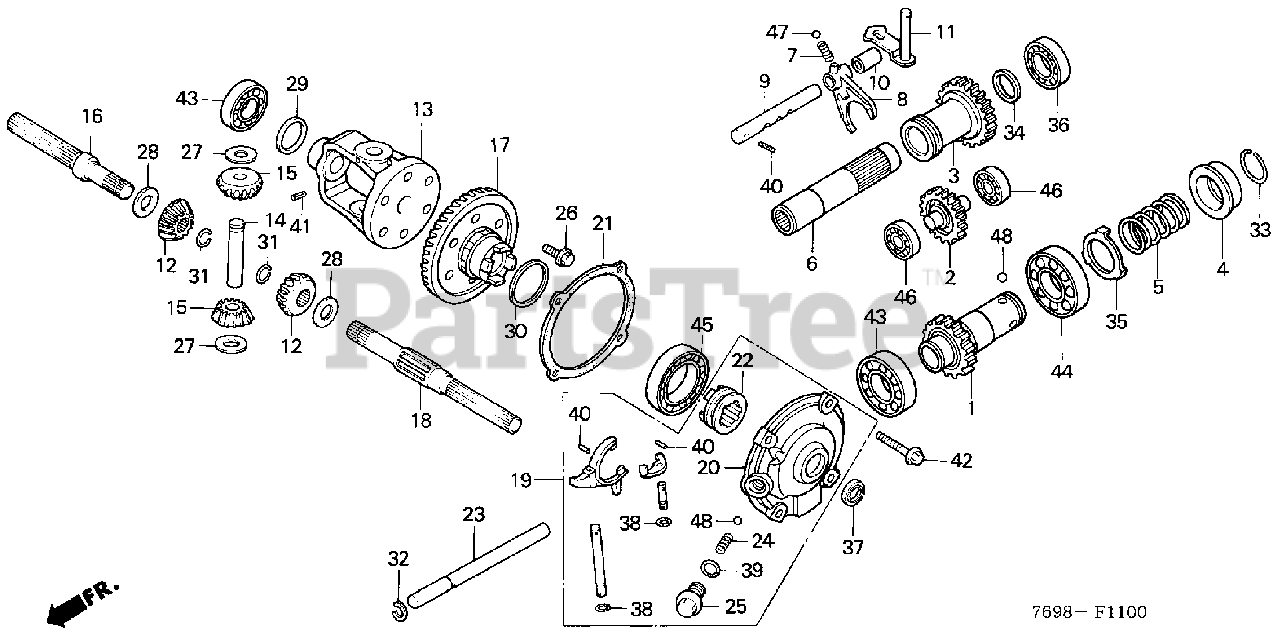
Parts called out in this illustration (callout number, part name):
1	SHAFT, P.T.O. OUTPUT
2	SHAFT, P.T.O. IDLE
3	GEAR, P.T.O. CHANGE
4	COLLAR, P.T.O. TUBE
5	SPRING, P.T.O. TUBE
6	SHAFT, P.T.O. INPUT
7	SPRING B, BALL SETTING
8	FORK, P.T.O. SHIFT
9	SHAFT, P.T.O. SHIFT
10	COLLAR, P.T.O. SHAFT
11	ARM, P.T.O. SHIFT
12	GEAR, DIFFERENTIAL (14T)
13	CASE, RR. DIFFERENTIAL
14	SHAFT, DIFFERENTIAL PINION
15	PINION, DIFFERENTIAL (14T)
16	SHAFT, R. RR. DRIVE
17	GEAR, RR. DIFFERENTIAL DRIVEN
18	SHAFT, L. RR. DRIVE
19	HOLDER, DIFFERENTIAL BEARING
21	GASKET, DIFFERENTIAL BEARING HOLDER
22	SHIFTER, DIFFERENTIAL LOCK
23	SHAFT, DIFFERENTIAL LOCK
24	SPRING, DIFFERENTIAL LOCK FORK
25	SCREW, BALL SET SPRING
26	BOLT, HEX. (10MM)
27	WASHER A, DIFFERENTIAL PINION (16.2X30X0.7)
27	WASHER B, DIFFERENTIAL PINION (16.2X30X0.8)
27	WASHER C, DIFFERENTIAL PINION (16.2X30X0.9)
27	WASHER D, DIFFERENTIAL PINION (16.2X30X1.0)
28	WASHER, DIFFERENTIAL GEAR
29	SHIM, RR. DIFFERENTIAL CASE (35.5X45X1.0) (A)
29	SHIM, RR. DIFFERENTIAL CASE (35.5X45X1.1) (B)
29	SHIM, RR. DIFFERENTIAL CASE (35.5X45X1.2) (C)
29	SHIM, RR. DIFFERENTIAL CASE (35.5X45X1.3) (D)
29	SHIM, RR. DIFFERENTIAL CASE (35.5X45X1.4) (E)
29	SHIM, RR. DIFFERENTIAL CASE (35.5X45X1.5) (F)
29	SHIM, RR. DIFFERENTIAL CASE (35.5X45X1.6) (G)
29	SHIM, RR. DIFFERENTIAL CASE (35.5X45X1.7) (H)
29	SHIM, RR. DIFFERENTIAL CASE (35.5X45X1.8) (I)
29	SHIM, RR. DIFFERENTIAL CASE (35.5X45X1.9) (J)
29	SHIM, RR. DIFFERENTIAL CASE (35.5X45X2.0) (K)
29	SHIM, RR. DIFFERENTIAL CASE (35.5X45X2.1) (L)
30	SHIM, PINION (45.5X51.5X1.45) (C)
30	SHIM, PINION (45.5X51.5X1.5) (D)
30	SHIM, PINION (45.5X51.5X1.55) (E)
30	SHIM, PINION (45.5X51.5X1.6) (F)
30	SHIM, PINION (45.5X51.5X1.65) (G)
30	SHIM, PINION (45.5X51.5X1.7) (H)
30	SHIM, PINION (45.5X51.5X1.75) (I)
30	SHIM, PINION (45.5X51.5X1.8) (J)
30	SHIM, PINION (45.5X51.5X1.85) (K)
30	SHIM, PINION (45.5X51.5X1.9) (L)
30	SHIM, PINION (45.5X51.5X1.95) (M)
30	SHIM, PINION (45.5X51.5X2.0) (N)
30	SHIM, PINION (45.5X51.5X2.05) (O)
30	SHIM, PINION (45.5X51.5X2.1) (P)
31	CIRCLIP (OUTER) (22MM)
32	CIRCLIP (OUTER) (12MM)
33	CLIP, P.T.O. OUTPUT
34	WASHER, INPUT SHAFT THRUST
35	WASHER, SPRING STOPPER
36	BEARING, RADIAL BALL (28X52X12) (KOYO)
37	OIL SEAL (26X39X7.9)
38	O-RING (6.8X1.9)
39	O-RING (14.8X2.4) (NOK)
40	PIN, SPRING (3X18)
41	PIN, SPRING (4X32)
42	BOLT, FLANGE (8X35)
43	BEARING, RADIAL BALL (6007)
44	BEARING, RADIAL BALL (6008)
45	BEARING, RADIAL BALL (6009)
46	BEARING, RADIAL BALL (6203)
47	BALL, STEEL (#10) (5/16)
48	BALL, STEEL (#12) (3/8)
